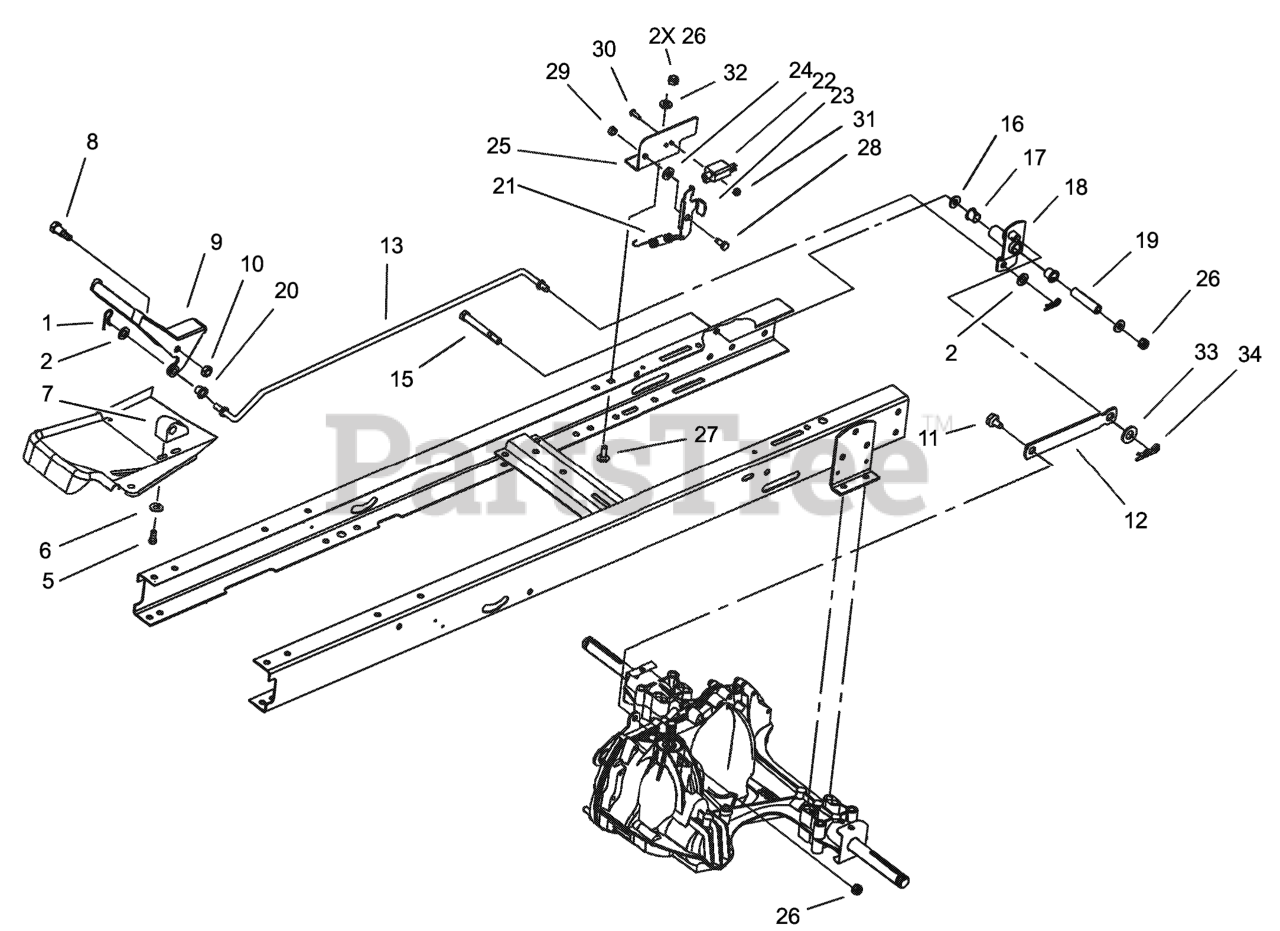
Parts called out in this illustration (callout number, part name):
1	PIN-COTTER
2	WASHER-FLAT
5	SCREW-PLASTITE
6	WASHER-FLAT
7	BLOCK-PIVOT
8	SCREW-SHOULDER, HH
9	PEDAL-CONTROL, SPEED
10	NUT-LOCK, NI
11	BOLT-SHOULDER
12	LINK-CONTROL, SPEED
13	ROD-CONTROL, SPEED
15	SCREW-HH
16	WASHER-FLAT
17	BUSHING-NYLINER
18	PIVOT ASM
19	SPACER-PIVOT
20	BUSHING-FLANGED
21	SPRING-EXTENSION
22	SWITCH-POLE, SINGLE
23	BRACKET-PIVOT
24	WASHER-STEPPED
25	BRACKET-ADJUSTMENT
26	NUT-LOCK, NI
27	SCREW-CARR
28	SCREW-HHF
29	NUT-LOCK, NI
30	SCREW-SHH
31	NUT-LOCK
32	WASHER-PLAIN
33	WASHER-FLAT
34	PIN-HAIR
